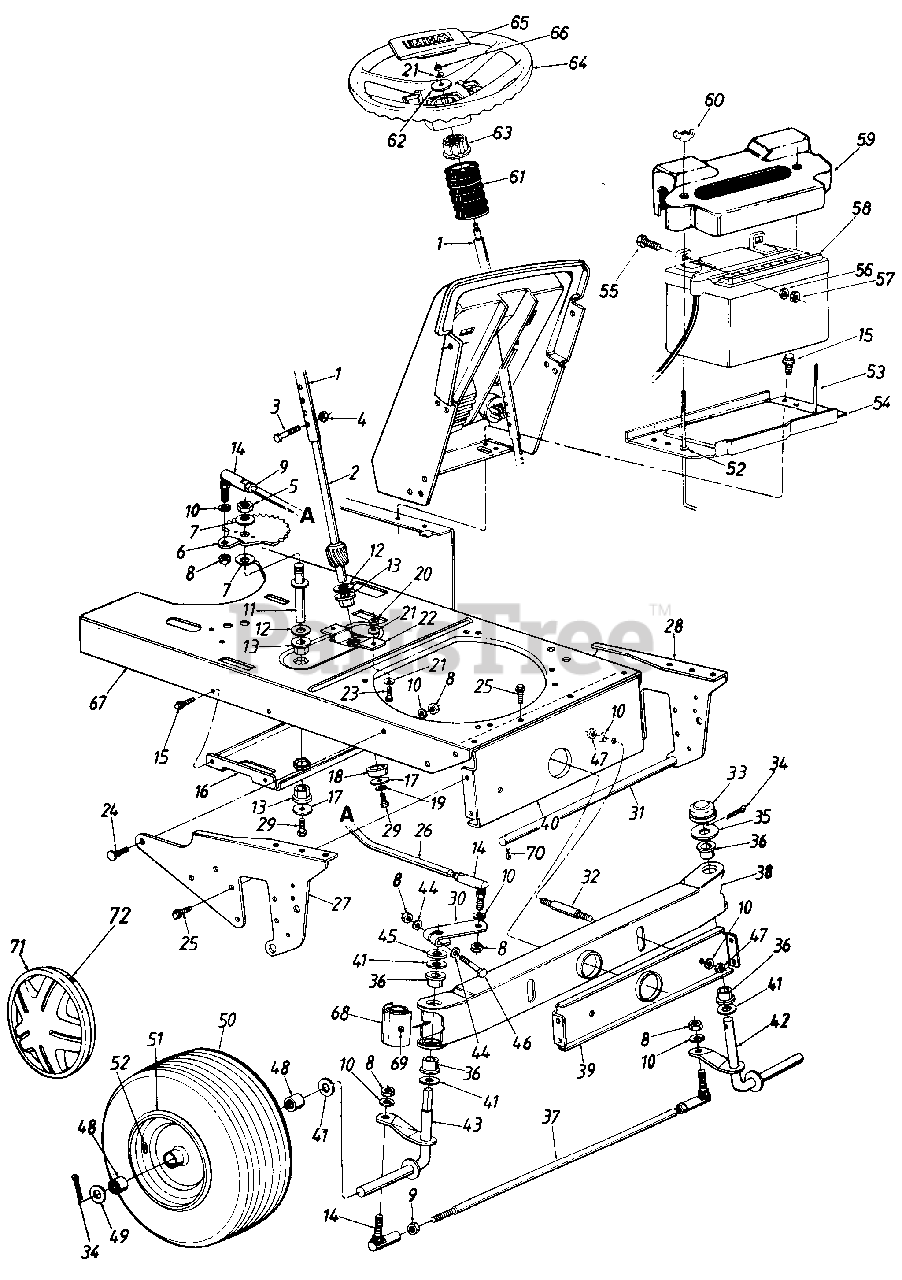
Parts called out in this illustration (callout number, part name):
1	Steering Column Ass'y.
2	Lower Steering Shaft
3	Hex Bolt 1/4-20 x 1.31" Lg.
4	Hex L-Nut 1/4-20 Thd.
5	Hex Nut 5/8-18 Thd.
6	Steering Gear Segment
7	Bell-Wash. 5/8" I.D. x 1.25" O.D.
8	Hex Nut 3/8-24 Thd.
9	Hex Jam Nut 3/8-24 Thd.
10	L-Wash. 3/8" I.D.
11	Steering Gear Segment Shaft
12	Fl-Wash. .64" I.D. x 1.24" O.D.
13	Hex Flange Brg. .63" I.D.
14	Ball Joint Ass'y.
15	Hex Wash. Hd. TT-Tap Scr. 1/4-20 x .5" Lg.
16	Deck Idler Support Brkt.
17	Fl-Wash. .33" I.D. x 1.25" O.D.
18	Spacer .985" I.D. x 1.25" O.D.
19	L-Wash. 5/16" I.D.
20	Hex Nut 5/16-24 Thd.
21	Bell-Wash. .345" I.D. x .88" O.D.
24	Ribbed Neck Bolt 3/8-24 x .8" Lg.
25	Hex Wash. TT-Tap Scr. 5/16-18 x .62" Lg.
26	Steering Drag Link
27	Pivot Bar Side Plate-R.H.
28	Pivot Bar Side Plate-L.H.
29	Hex Bolt 5/16-18 x .62" Lg.
30	Steering Arm
31	Deck Connecting Rod
32	Pivot Bar Shld. Bolt 3/8-16 x 518" Lg.
33	Cap
34	Cotter Pin 5/32" Dia.
36	Flange Brg. .757" I.D.
37	Tie Rod 20.25" Lg.
38	Pivot Bar Assy.
41	Fl-Wash. .76" I.D. x 1.49" O.D.
42	Front Axle Ass'y.-L.H.
43	Front Axle Ass'y.-R.H.
44	Bowed Washer
45	Spacer .755" I.D. x 1.25" O.D.
46	Hex Bolt 3/8-24 x 2.25" Lg.
47	Hex Nut 3/8-16 Thd.
48	Needle Brg. .75" I.D.
49	Fl-Wash. .71" I.D. x 1.5" O.D.
50	Wheel Ass'y. Comp.
52	Push Nut
53	Battery Hold Down Rod
54	Battery Carrier
55	Hex Bolt 1/4-20 x .62" Lg.
56	L-Wash. 1/4" I.D.
57	Hex Nut 1/4-20 Thd.
58	Battery
59	Battery Cover
60	Wing Nut Plastic 1/4-20 Thd.
61	Steering Bellow
62	Flat Washer
63	Steering Wheel Adapter
64	Steering Wheel
65	Steering Wheel Cap
66	Hex L-Nut 5/16-24 Thd.
67	Lower Frame
68	Pivot Bar End Cap
69	Grease Fitting
70	Internal Cotter Pin
72	Spring Clip
